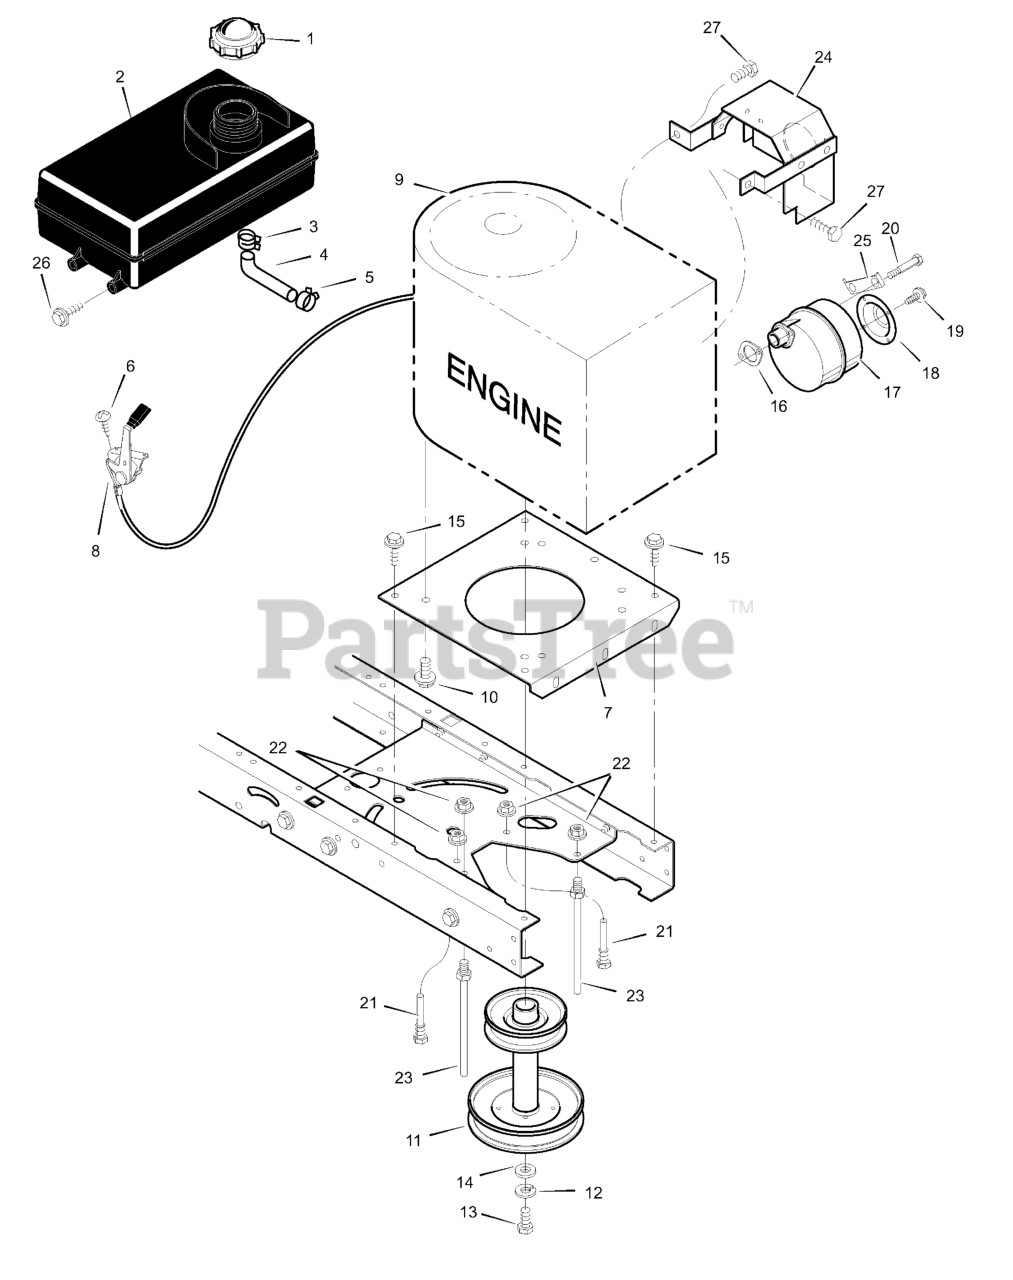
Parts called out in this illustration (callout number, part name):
1	Fuel Cap
2	TANK, Fuel 1.4 Gal.
3	Hose Clamp
4	Fuel Line
5	Hose Clamp
7	Plate, Engine
8	Throttle Control
9	Engine *
10	Bolt, Engine Mount
11	STACK PULLEY ASSEMBLY
12	Lockwasher
13	Bolt, Hex
16	GASKET, Exhaust
17	Muffler
18	Deflector, Muffler
20	Bolt, Hex
21	Guide, Belt
22	Nut, Flange
23	Guide, Belt
24	Shield, Heat
25	Lock, Screw
